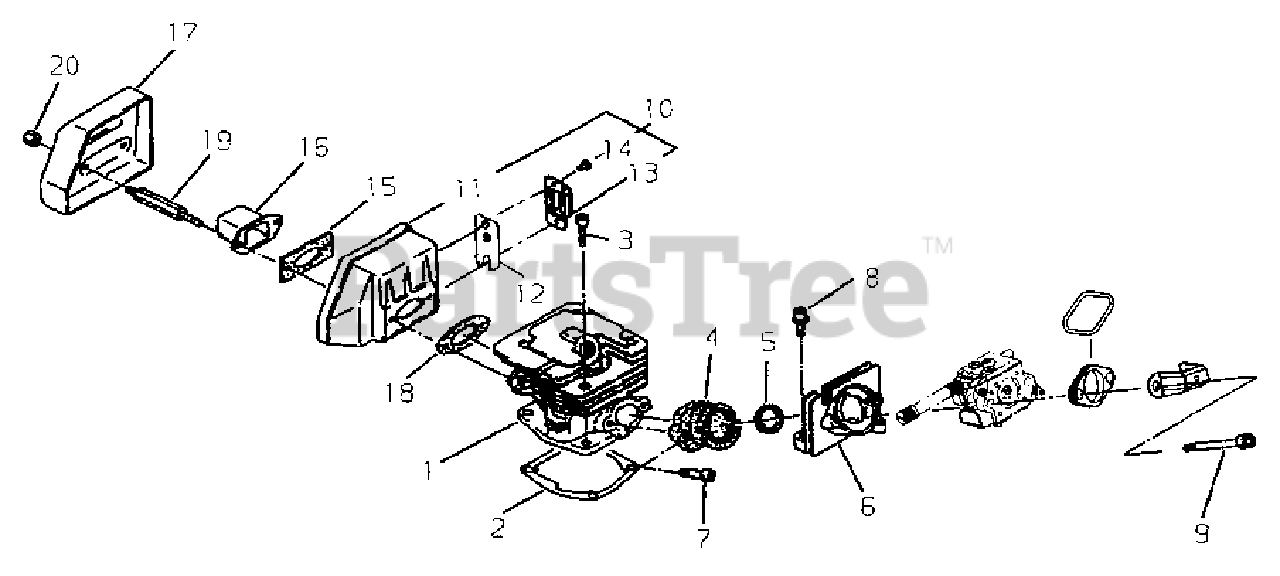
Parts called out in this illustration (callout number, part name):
1	CYLINDER
2	GASKET, CYLINDER
4	BOOT
5	COLLAR 16
6	BRACKET
7	BOLT, ADHESIVE M4×12
8	BOLT, ADHESIVE M4×14
9	SCREW
10	BASE ASSY, MUFFLER
11	BASE, MUFFLER
12	SCREEN, SPARK ARRESTER
13	COVER, SPARK ARRESTER
14	SCREW M4×6
15	PLATE, MUFFLER
16	PIPE, EXHAUST
17	COVER, MUFFLER
18	GASKET, MUFFLER
19	BOLT
20	NUT M5×6.3
